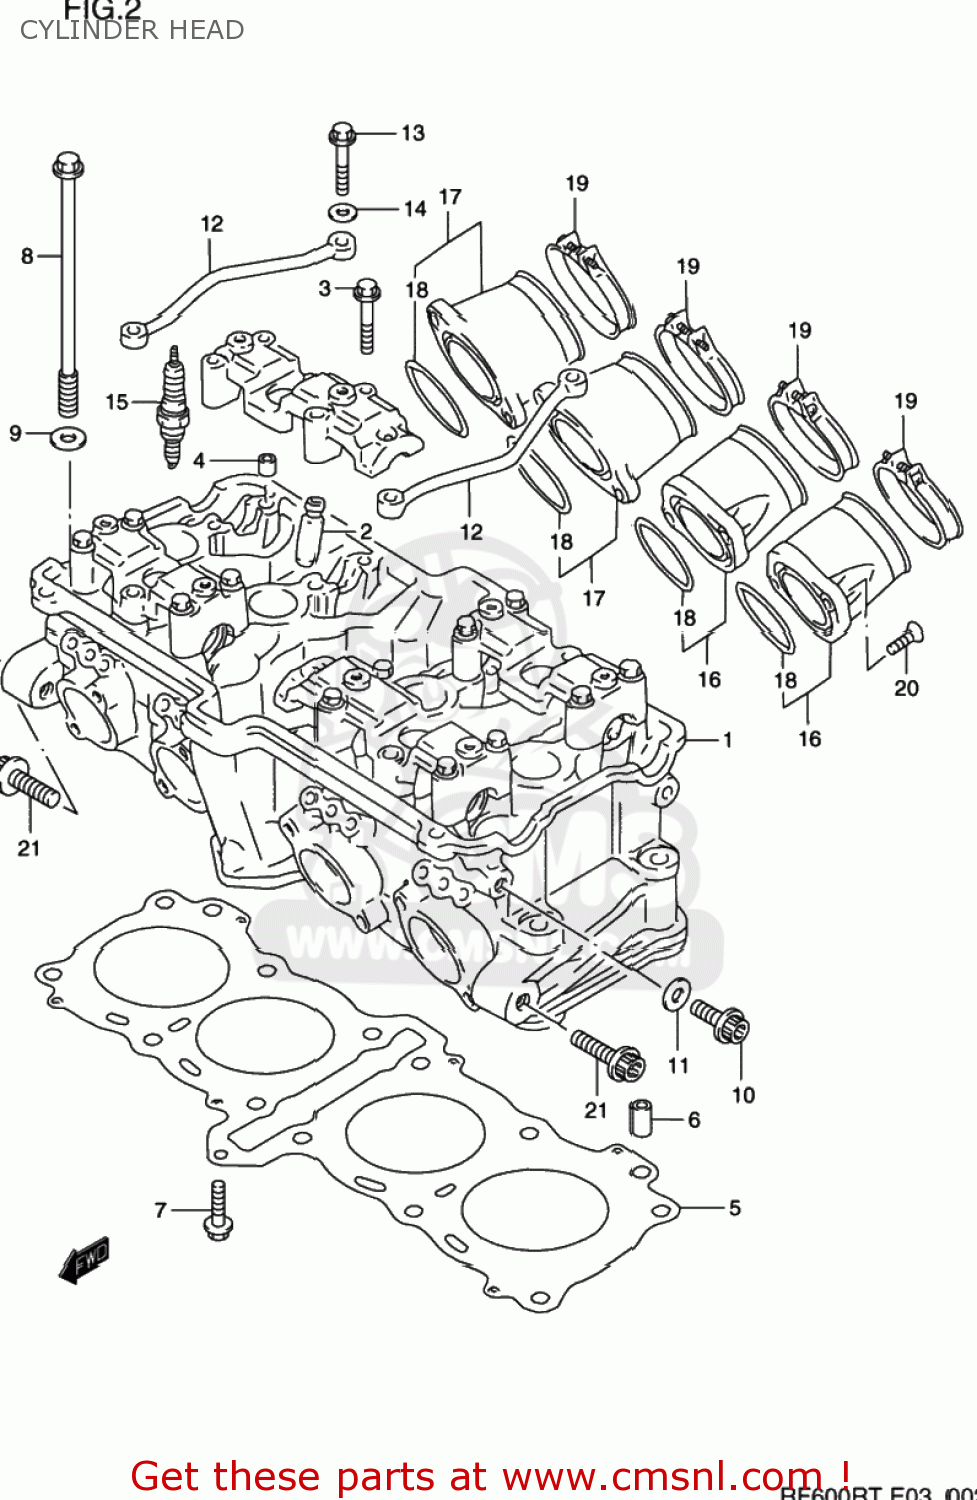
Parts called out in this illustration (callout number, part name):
1	HEAD ASSEMBLY,CYLINDER
2	GUIDE,VALVE
3	BOLT(6X45)
4	PIN(6.2X8X11)
5	GASKET,CYLINDER HEAD
6	PIN
7	BOLT
8	BOLT(10X160)
9	WASHER(10.5X19X2)
10	BOLT
11	GASKET(8.2X14X1).6 (NAS)
12	PIPE,CYLINDER HEAD OIL
13	BOLT(6X39)
14	WASHER
15	PLUG,SPARK(CR8E)
16	PIPE ASSY,INTAKE NO.1
17	PIPE ASSY,INTAKE NO.2
18	O RING(D:2.4,ID:41.7)
19	CLAMP
20	SCREW
21	BOLT
